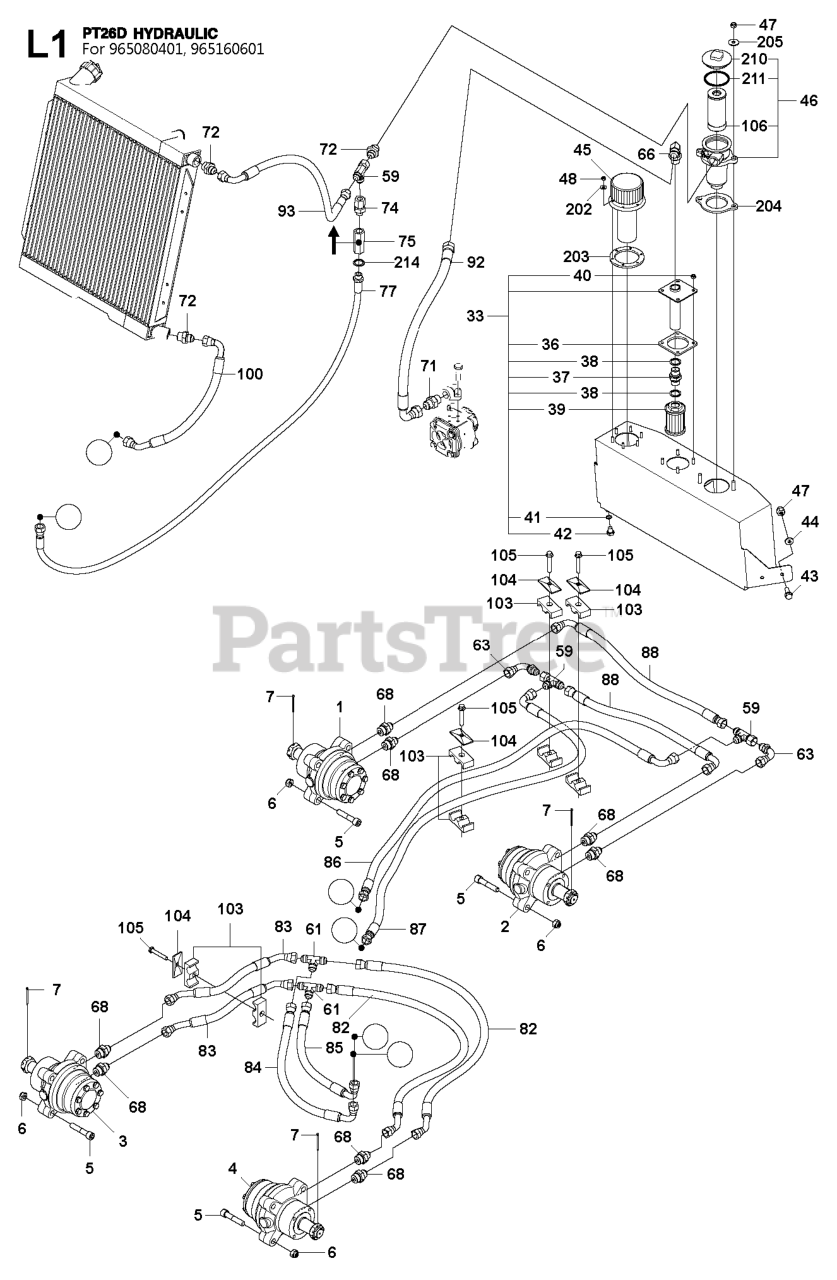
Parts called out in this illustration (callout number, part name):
1	WHEEL MOTOR 125 CW
2	WHEEL MOTOR 125 CCW
3	WHEEL MOTOR 160 CW
4	WHEEL MOTOR 160 CCW
7	COTTER PIN
33	HYDRAULIC TANK ASSY
37	PIPE FITTING G STRAIGHT 1/2-1/
39	FILTER PUMP SUCTION, AWD
40	LOCKNUT M6
41	GASKET 14X10.5X1 COPPER
42	SCREW EHHM
46	FILTER HOLDER
47	LOCKNUT M8
48	LOCKNUT M5
61	PIPE FITTING JIC T 3/4"
74	PIPE FITTING JIC-BSPP STRAIGHT
75	CHECK VALVE 2BAR
105	BOLT FLANGE - M8X50
202	WASHER
205	WASHER BRB 8.4X17
